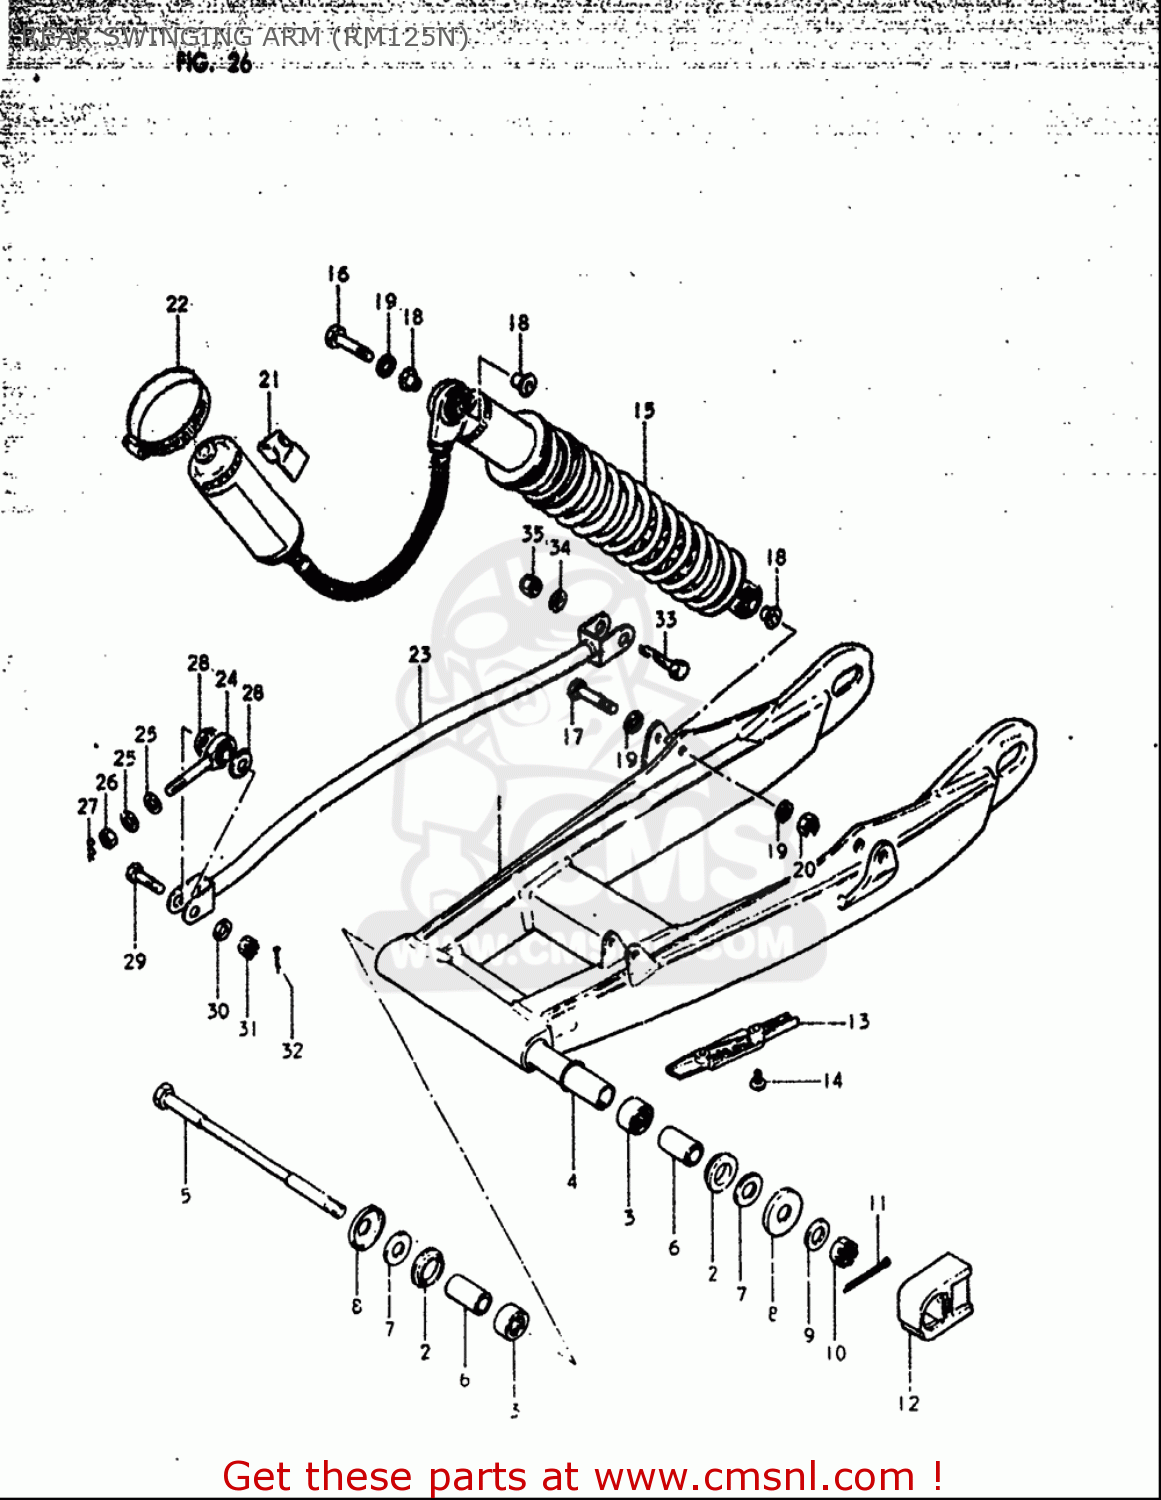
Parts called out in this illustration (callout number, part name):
2	BUSH,RR SWINGINGARM PIVOT
3	BEARING(17X24X20)
4	SPACER
5	SHAFT,RR SWINGINGARM PIVOT
6	SPACER,RR SWGARM PIVOT
7	WASHER
8	COVER,REAR SWING ARM DUST
9	WASHER
10	NUT
11	COTTER PIN
12	BUFFER,CHAIN TOUCH DEFLECTOR
14	SCREW
17	BOLT(8X46)
18	SPACER,RR SHK ABS INNER
19	WASHER
20	NUT
21	CUSHION,RR SHOCK ABSORBER
25	WASHER
26	NUT
27	PIN
28	DUST SEAL,TORQUE LINK FR BRG
30	WASHER
31	NUT
32	PIN
33	BOLT
34	WASHER
35	NUT
